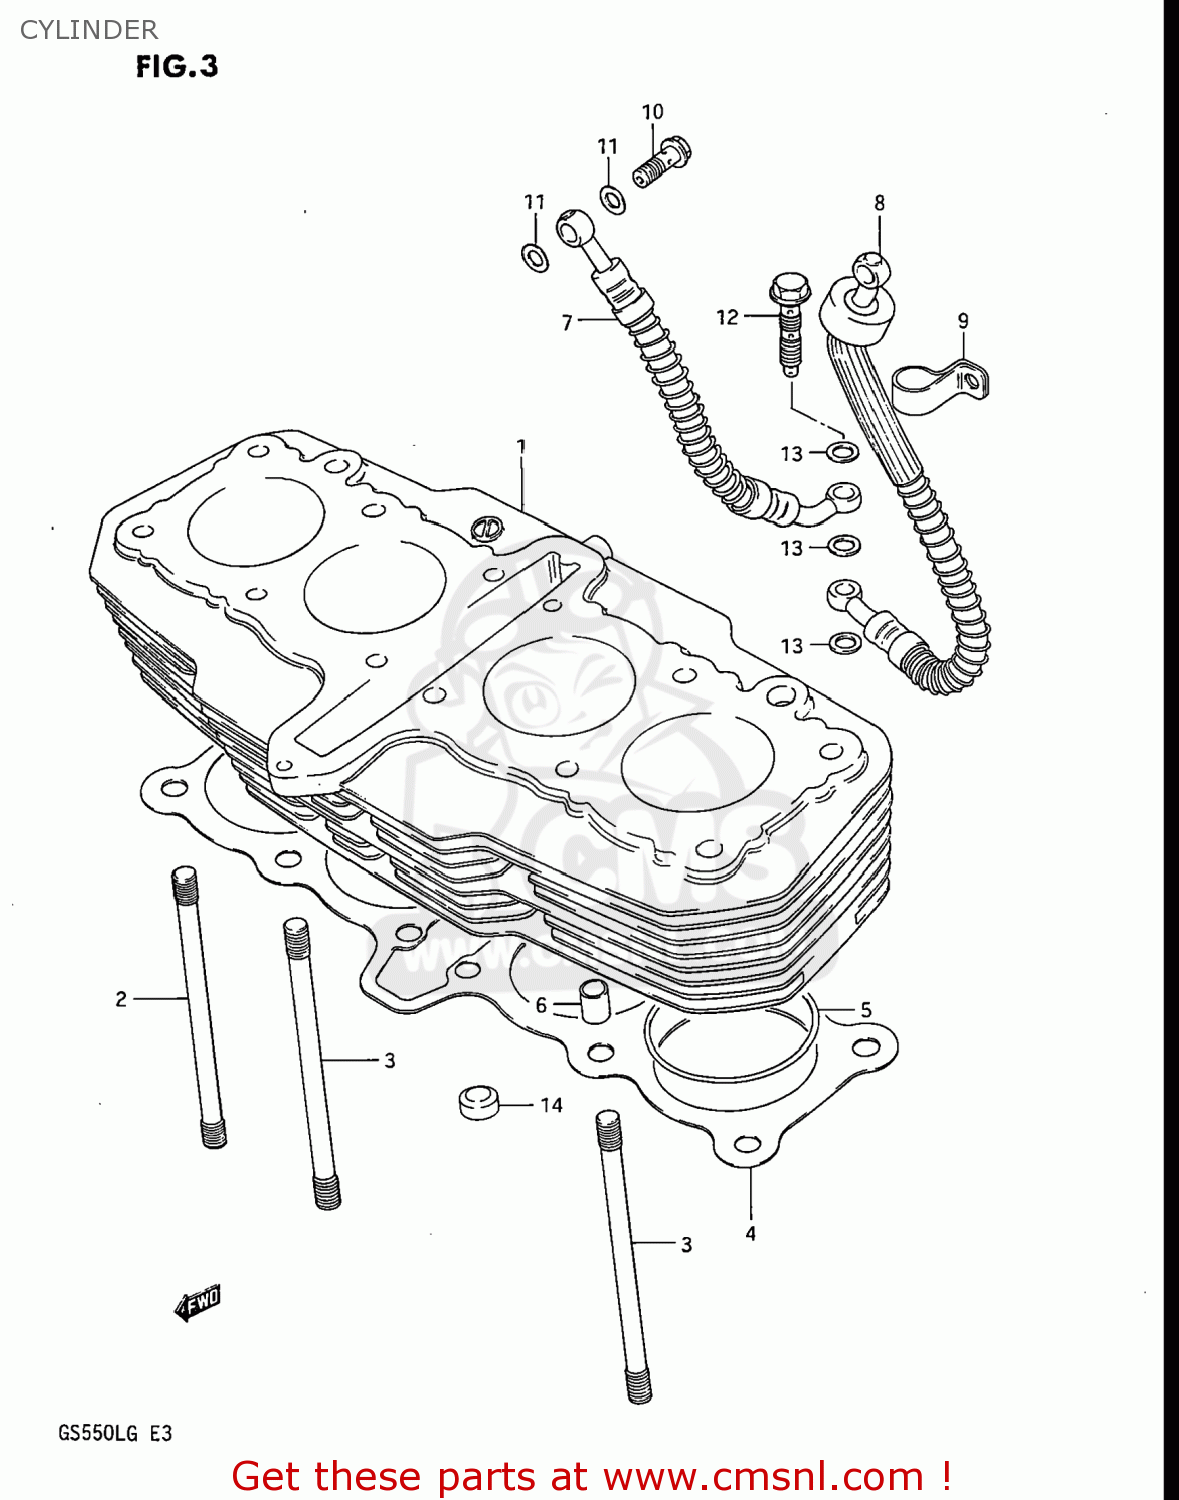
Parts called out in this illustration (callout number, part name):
1	CYLINDER
2	STUD
3	BOLT,STUD
4	GASKET,CYLINDER (MCA)
5	O RING(D:2,ID:61)
6	PIN
7	HOSE,OIL CRANKCASE,R
8	HOSE,OIL CRANKCASE,L
9	CLAMP,OIL HOSE CRANKCASE
10	BOLT UNION
11	GASKET 8.2X14X1 (NAS)
12	BOLT,OIL PIPE
13	WASHER(10X15X1.5)
14	PAD,CYLINDER HEAD
